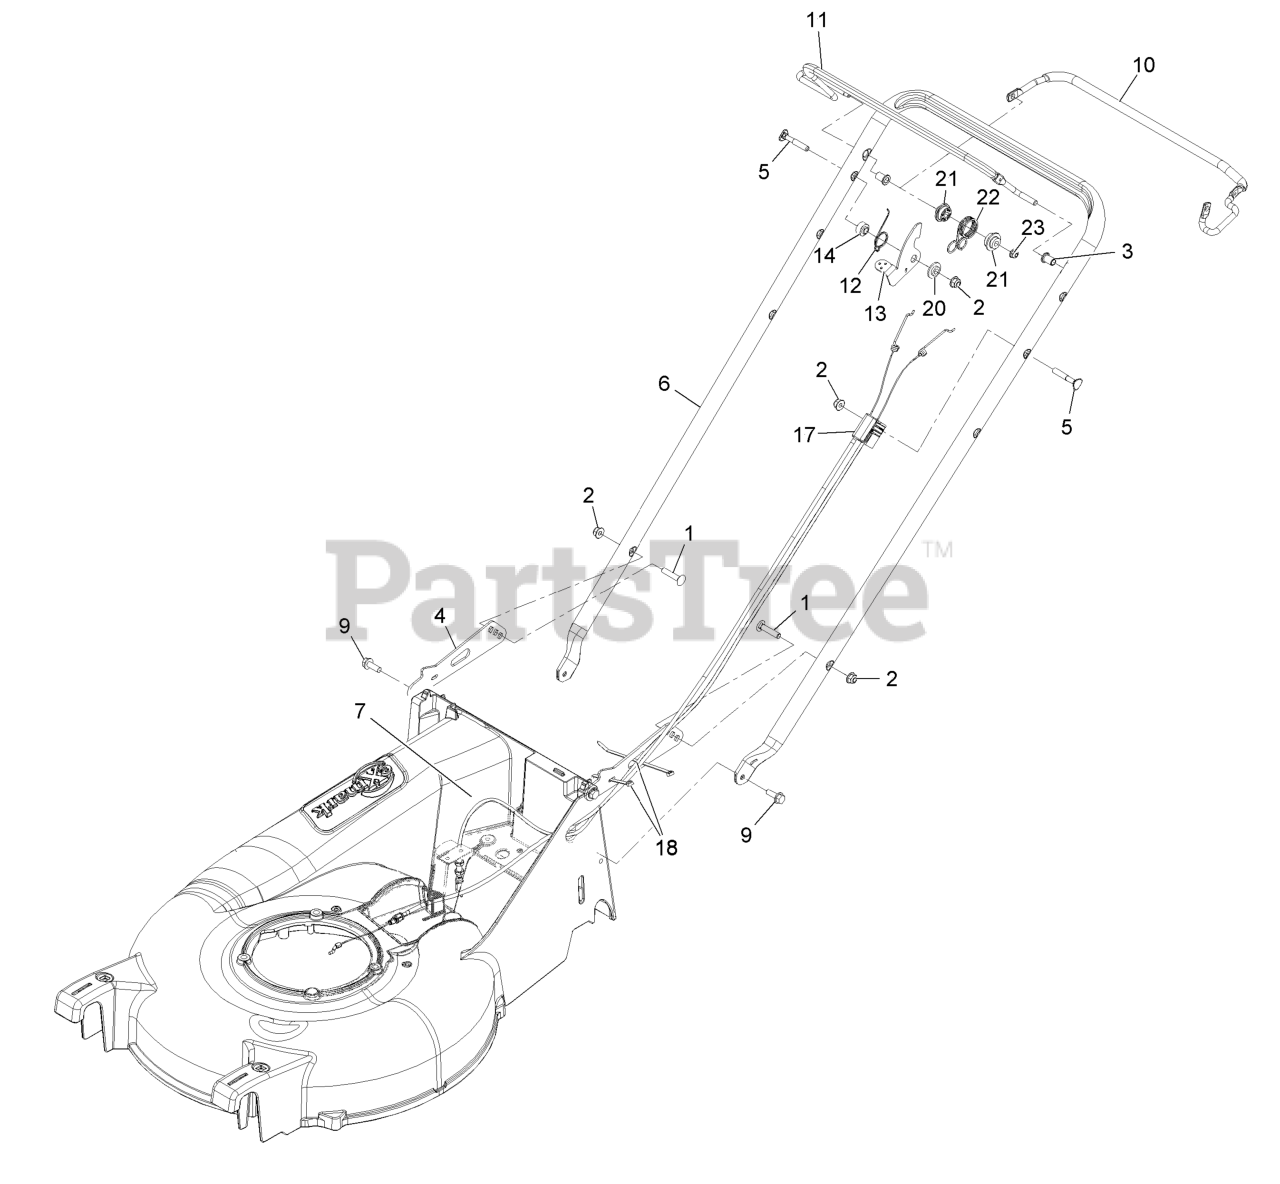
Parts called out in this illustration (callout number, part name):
1	Bolt-Carriage 5/16-18 X 1 1/2
2	Nut-Nyloc 5/16-18 Flg
3	Bushing-Handlebar
4	Bracket,Handlebar
5	Bolt-Carriage 5/16-18 X 2
6	Handlebar-P21
7	Cable, Drive Ec21
9	Screw-HWH 3/8-16 X 7/8 Taptite
10	Bail-Drive Coated
12	Spring-Lever, BBC
13	Lever-BBC
14	Bushing-Stepped
17	Cable-BBC
18	Tie-Cable
20	Washer-Stepped
21	Bushing-Spring, Pivot
22	Spring,BBC Return
23	Nut-Nyloc 1/4-20 Flg
